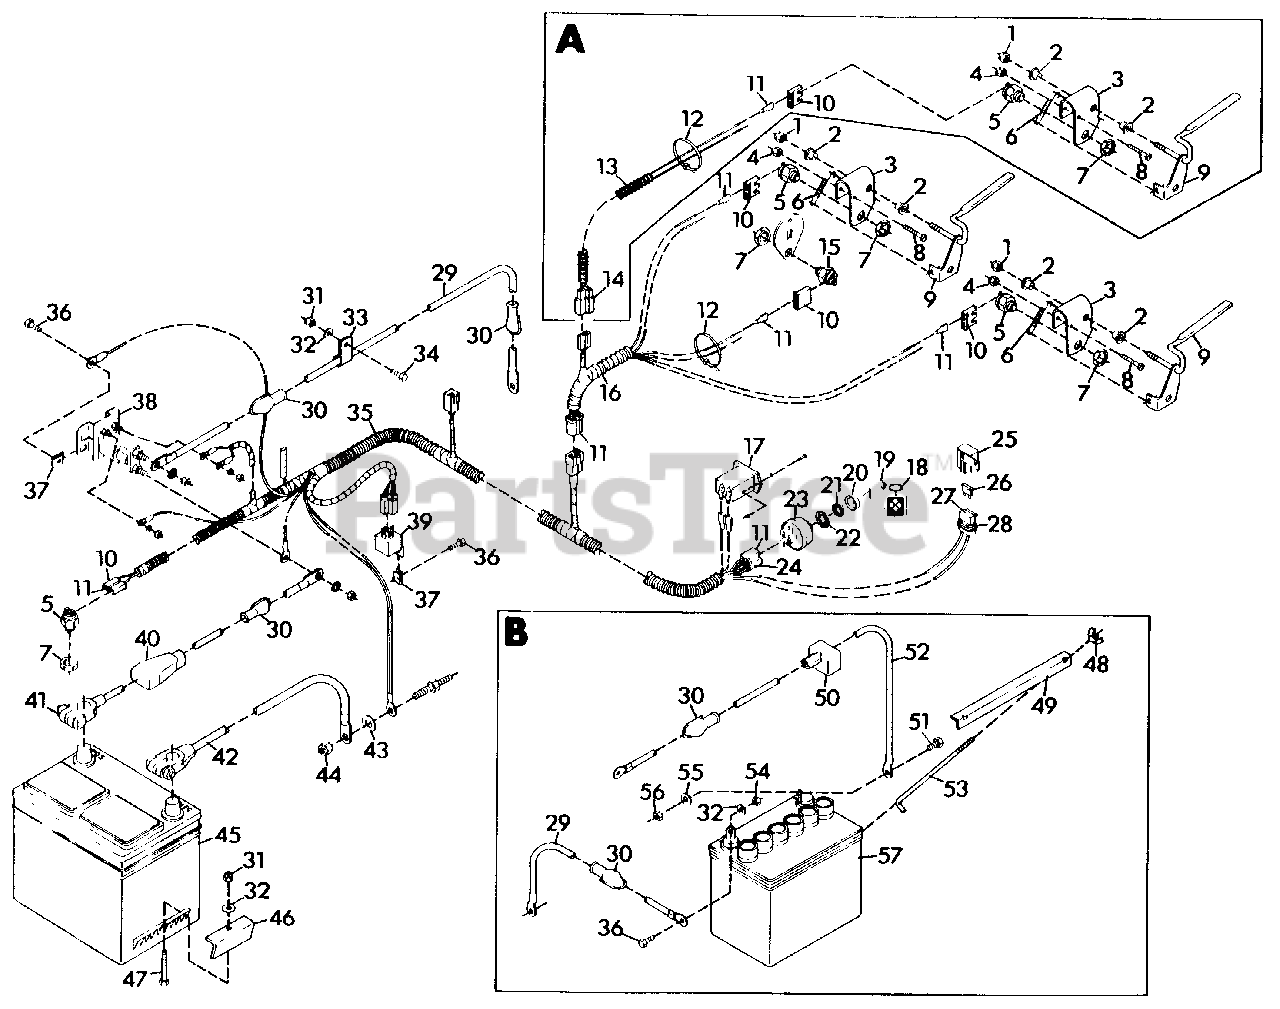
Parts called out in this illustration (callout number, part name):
1	NUT, LOCK 5/16-18
2	BUSHING, INTERLOCK LEVER
3	BRACKET, INTERLOCK MOUNTING
4	NUT, LOCK 10-24
5	SWITCH, INTERLOCK
6	SPRING, INTERLOCK LEVER
7	NUT, STAMPED 9/16-18
8	SCREW, MACH. 10-24X1.50 PHD
9	WELDMENT, HANDLE
10	CONNECTOR, 2-WIRE SWITCH
11	TERMINAL
12	TIE WRAP, BLACK
13	HARNESS, STEERING BRAKE
14	CONNECTOR
15	SWITCH, NEUTRAL START
16	HARNESS, WIRING HANDLEBAR
17	HOURMETER
18	CHAIN, KEY
19	KEY, IGNITION SWITCH
20	BOOT, FOR 9/16 SWITCH
21	NUT, 9/16-24 FOR SWITCH
22	WASHER, LOCK
23	SWITCH, IGNITION
24	CONNECTOR
25	COVER
26	FUSE, 25 AMP
27	TERMINAL, FOR 10-12 GA. WIRE
28	CONNECTOR
29	CABLE, SWITCH TO STARTER
29	CABLE, NEGATIVE BATTERY
30	BOOT, BATTERY CABLE
31	NUT, LOCK 1/4-20
32	WASHER, FLAT .281X.625X.065
33	CLAMP, NYLON
34	BOLT, HEX 1/4-20X.75
35	HARNESS, WIRING
36	BOLT, HEX 1/4-20X.625
37	NUT, SPEED 1/4-20
38	SWITCH, MAGNETIC
39	RELAY
40	COVER, BATTERY TERMINAL
41	CABLE, POSITIVE BATTERY
42	CABLE, NEGATIVE BATTERY
43	WASHER, FLAT .469X.938X.065
44	NUT, LOCK 3/8-16
45	BATTERY, 12 BOLT
46	CLAMP
47	BOLT, HEX 1/4-20X2.00
48	NUT, WING 1/4-20
49	HOLD DOWN, BATTERY
50	BOOT, BATTERY CABLE
51	BOLT, HEX 5/16-18X.625
52	CABLE, BATTERY TO SOLENOID
53	HOOK, BATTERY HOLD DOWN
54	NUT, HEX 1/4-20
55	WASHER, FLAT .344X.688X.065
56	NUT, HEX 5/16-18
57	BATTERY, 12 VOLT
NS	DECAL, E.S. WARNING
